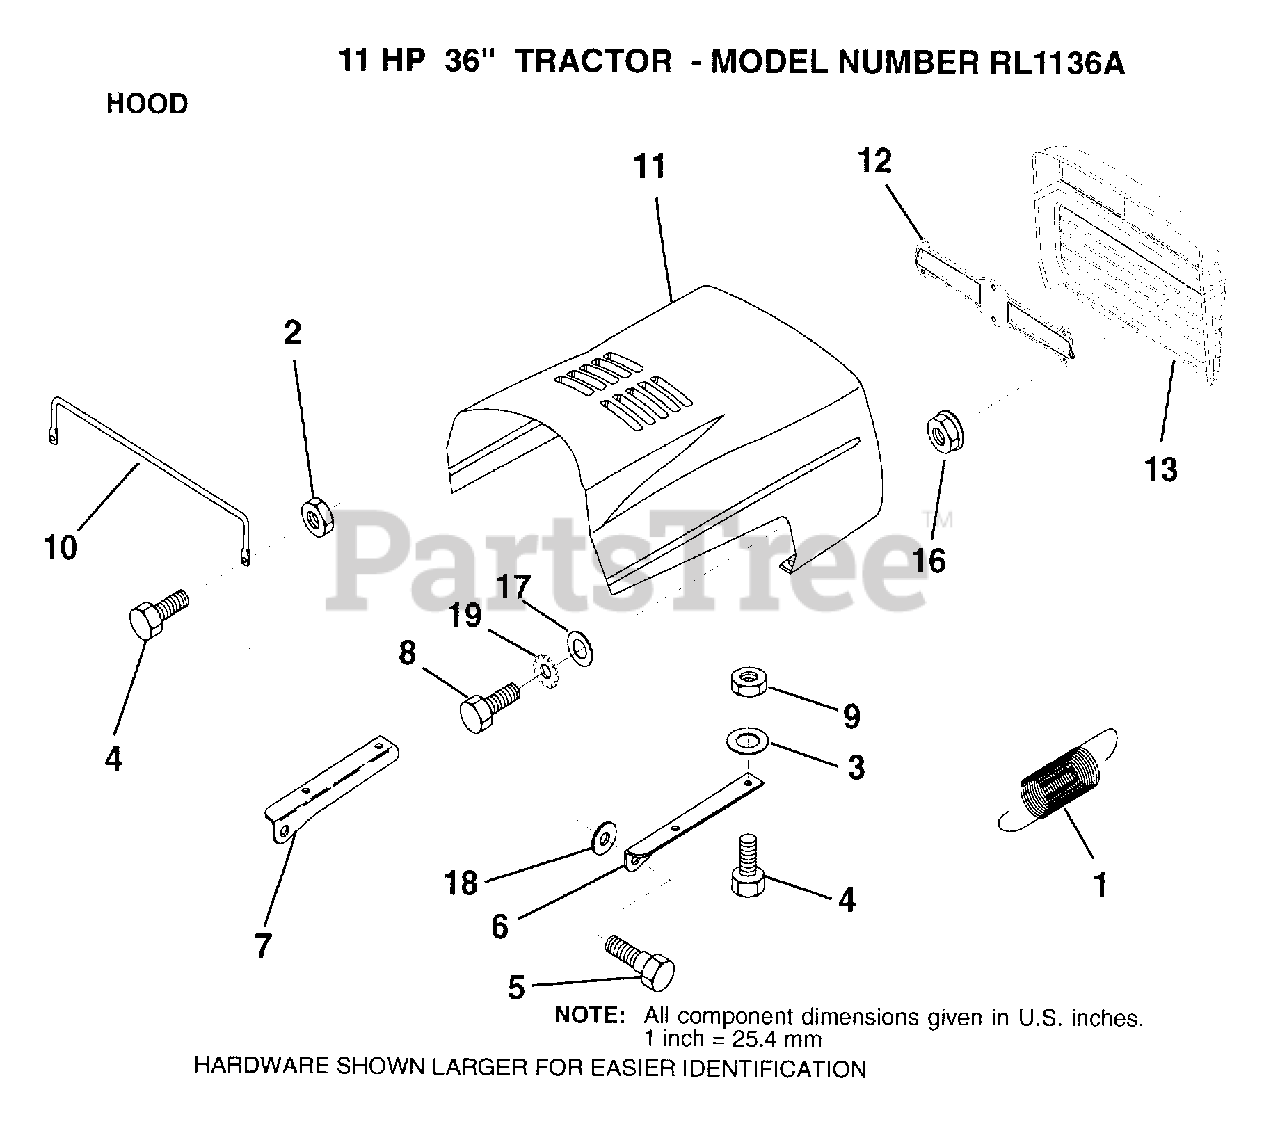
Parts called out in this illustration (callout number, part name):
1	EXT SPRING
2	NUT
3	WASHER
6	BRKT HOOD RH
7	BRKT HOOD LH
10	"BRACE,HOOD"
11	HOOD
16	NUT
17	WASHER
18	WASHER
19	LOCKWASHER GT
